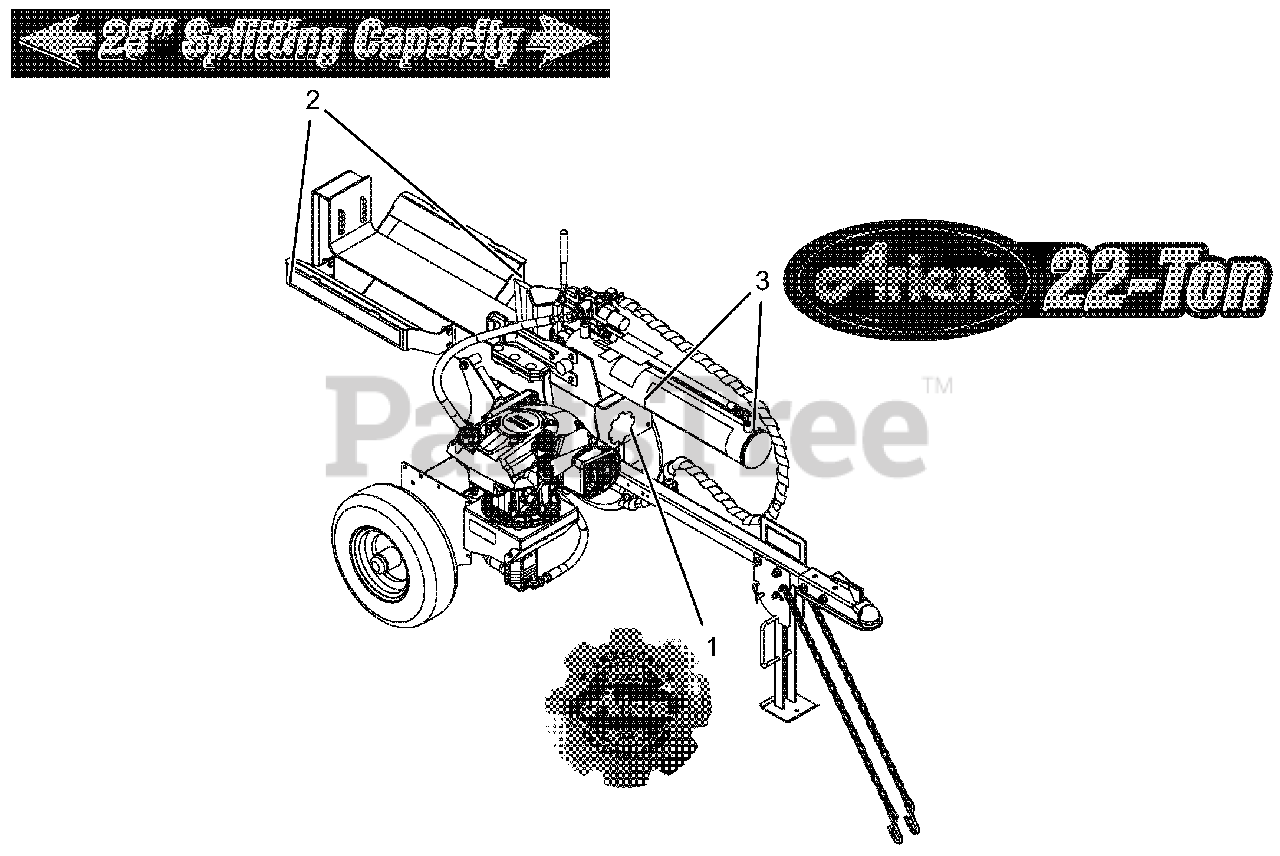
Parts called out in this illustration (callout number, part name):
1	DECAL, ARIENS HERITAGE-LARGE
2	DECAL, 25"SPLIT CAP
3	DECAL, 22TON/ARIENS LOGO
